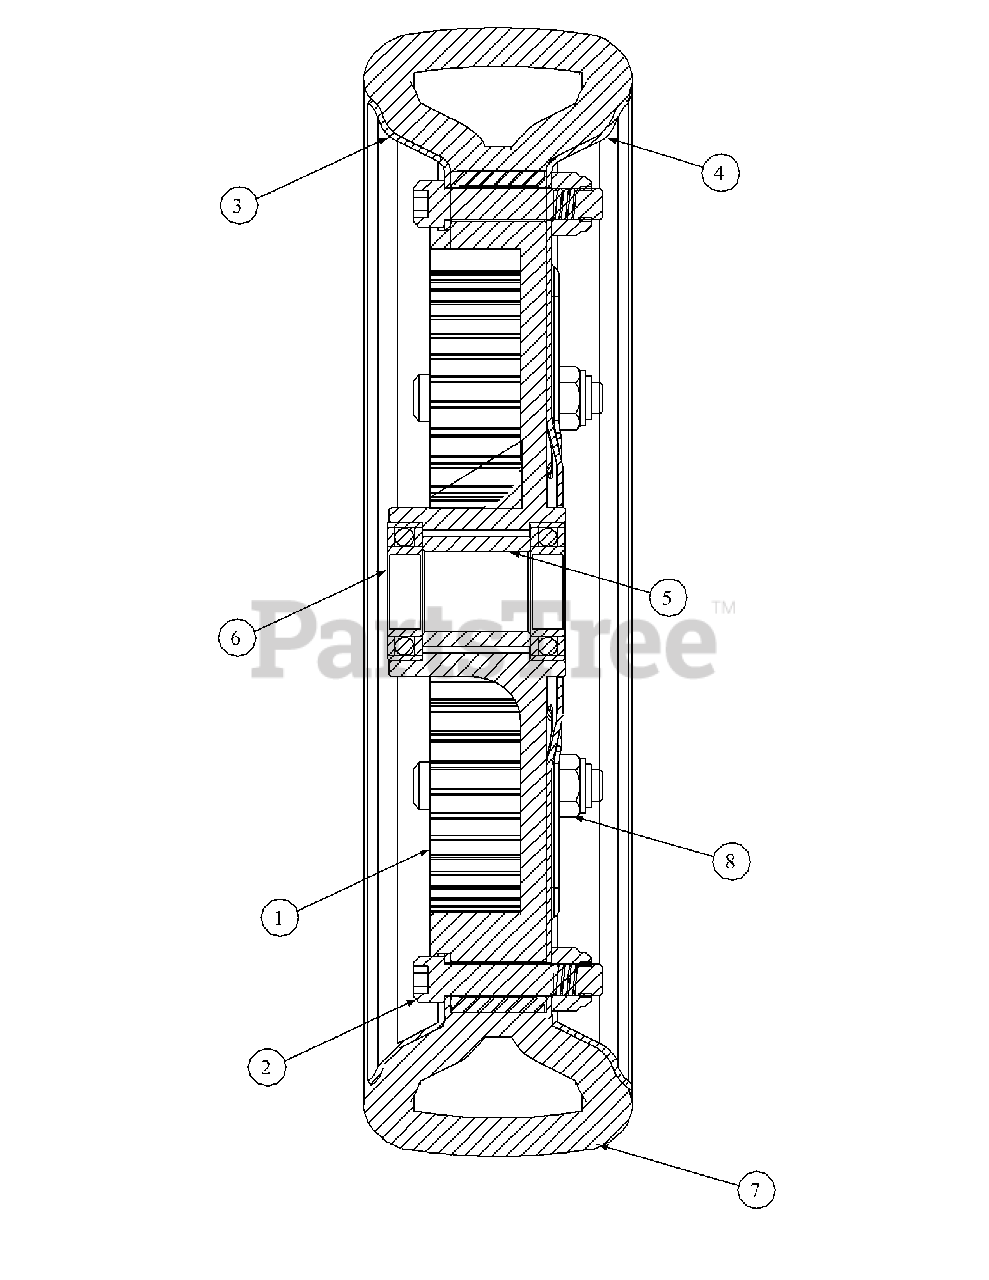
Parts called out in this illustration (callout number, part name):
1	non serviceable part
2	non serviceable part
3	non serviceable part
4	non serviceable part
5	Spacer, .635 ID x .86 Long
6	Ball Bearing, 15mm x 28mm x 7mm
7	Tire, 9 x 2.125
8	Hex, Lock Nut, 1/4-20
